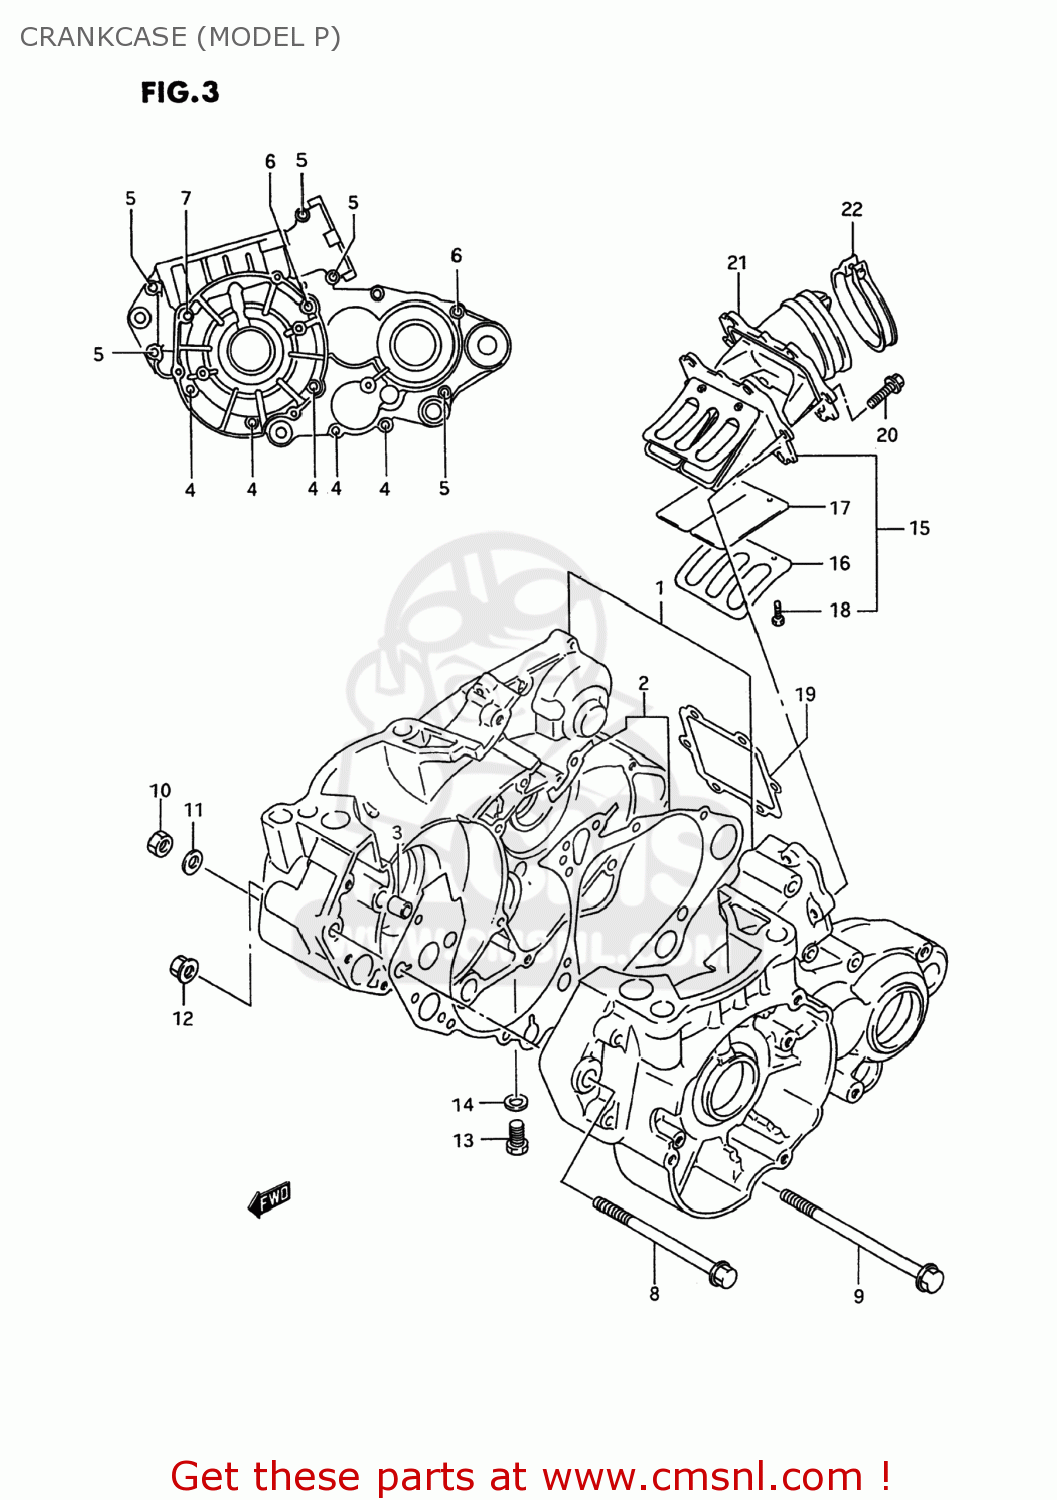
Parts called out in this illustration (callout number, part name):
1	CRANKCASE SET
2	GASKET,CRANKCASE (NAS)
3	PIN
4	BOLT
5	BOLT
6	BOLT
7	BOLT
8	BOLT(8X102)
9	BOLT 8X140
10	NUT
11	WASHER
12	NUT
13	BOLT,8X16
14	GASKET (NAS)
15	VALVE ASSEMBLY,REED
16	STOPPER,REED VALVE
17	VALVE,REED
18	SCREW
19	GASKET,REED VALVE (NAS)
20	BOLT
21	PIPE,INTAKE
22	CLAMP
